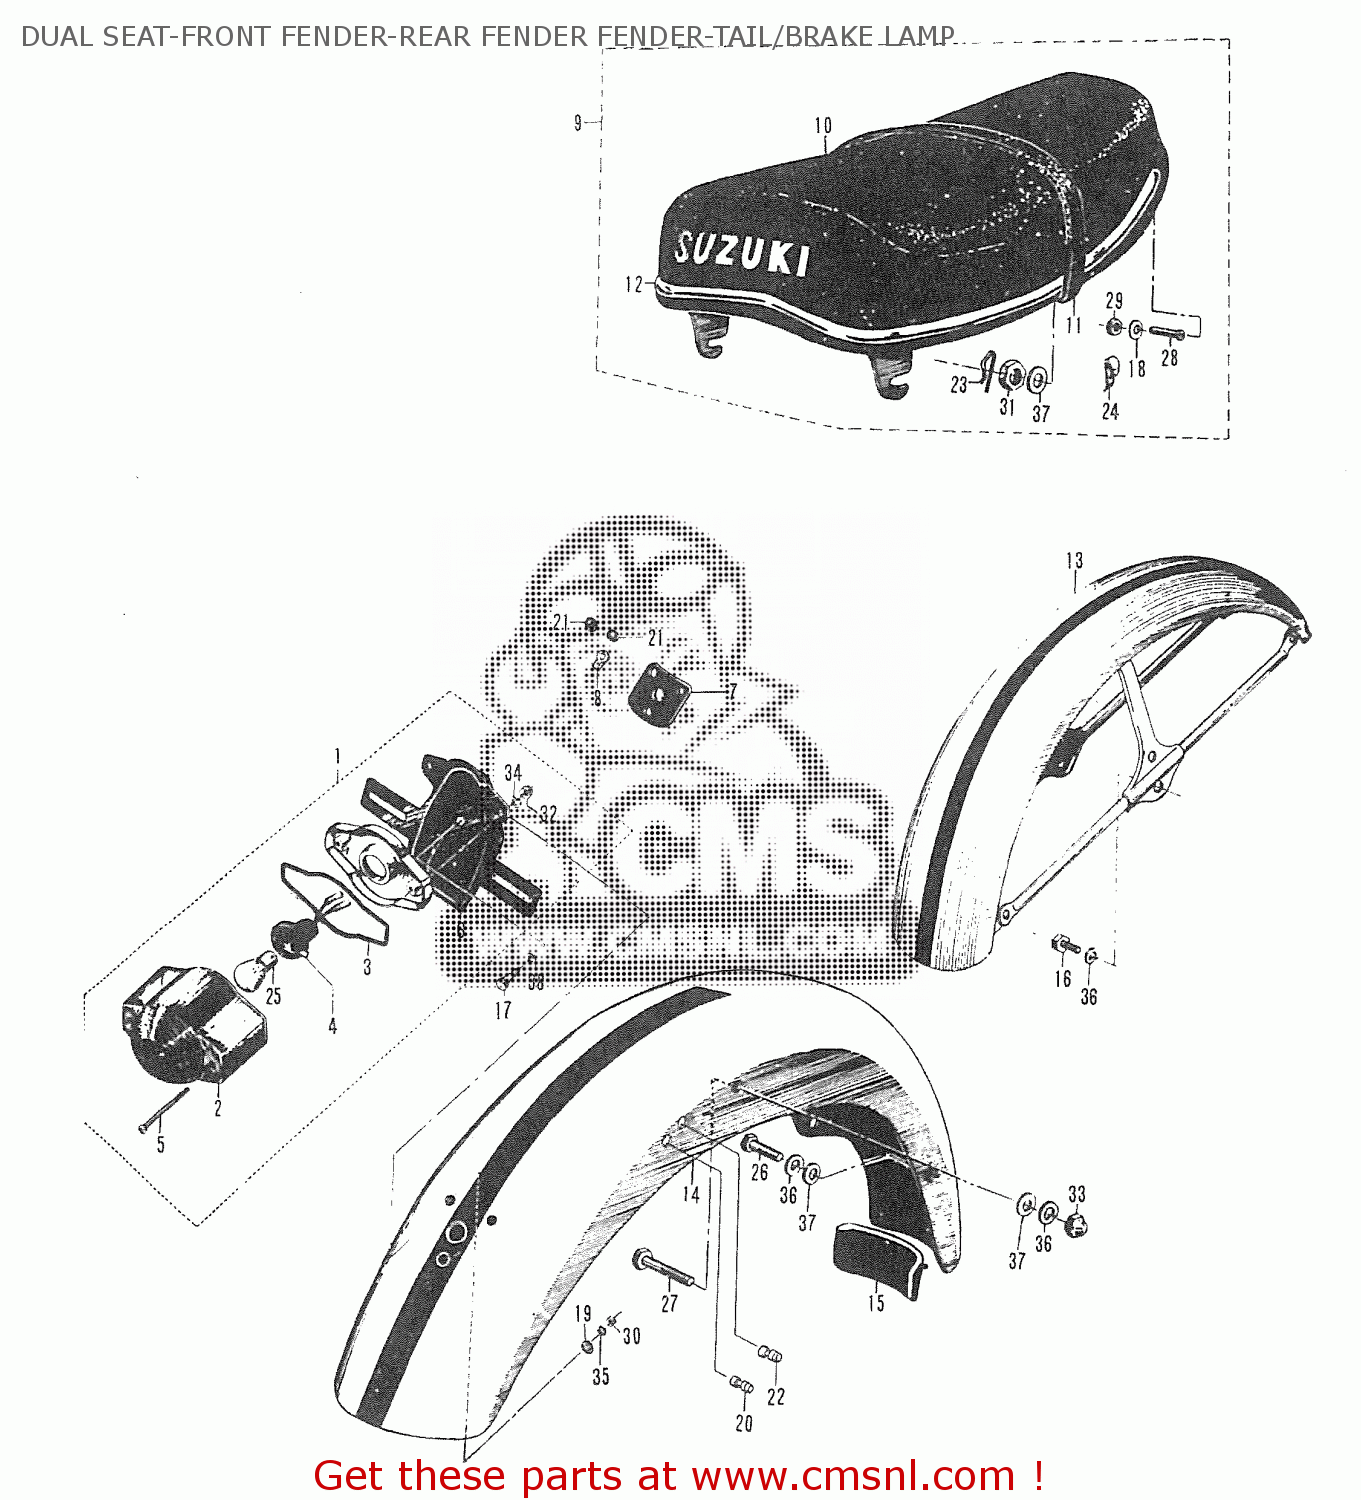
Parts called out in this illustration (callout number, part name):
1	LAMP ASSEMBLY,REAR COMBINATION
2	LENS,REAR COMBINATION LAMP
3	GASKET,REAR COMBINATION LAMP LENS (NAS)
4	HOUSING,REAR COMBINATION LAMP
5	3X51 CROSS HEAD SCREW
6	BRACKET,REAR COMBINATION LAMP
7	TAIL/BRAKE LAMP BUFFER
8	TAIL/BRAKE LAMP GROUNDING PIECE
9	DUEL SEAT ASS'Y
10	DUEL SEAT LEATHER
11	DUAL SEAT PASSENGER STRAP ASS'Y
12	DUEL SEAT RIM
13	FRONT FENDER
14	FENDER,REAR
15	MUD GUARD,REAR FENDER
16	FRONT FENDER BRACE BOLT
17	HEXAGON BOLT
18	WASHER
19	WASHER
20	PLUG
21	TAIL/BRAKE LAMP RUBBER WASHER
22	CUSHION
23	CLIP
24	DUAL SEAT LEATHER FITTING CLIP
25	BULB
26	SMALL HEAD HEXAGON BOLT
27	SMALL HEXAGON BOLT
28	CROSS HEAD SCREW
29	HEXAGON NUT
30	HEXAGON NUT
31	HEXAGON NUT
32	CROWN NUT
33	CROWN NUT
34	LOCK WASHER
35	LOCK WASHER
36	LOCK WASHER
37	SMALL FLAT WASHER
